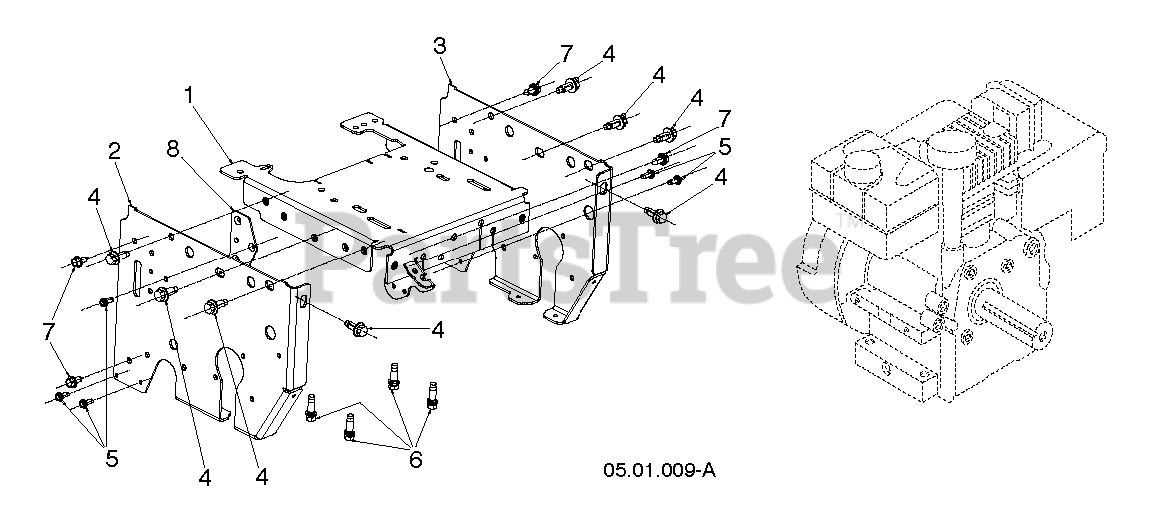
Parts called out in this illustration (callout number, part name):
4	SCREW HEXAGON HEAD FLANGE 3/8-
5	SCREW 14-20 X 5/8
6	BOLT 3/8-16X1-1/8
7	BOLT.HEX.HD.WASHER.5/16-18X.75
8	BRACKET NUT BLACK ZINC PLATE
